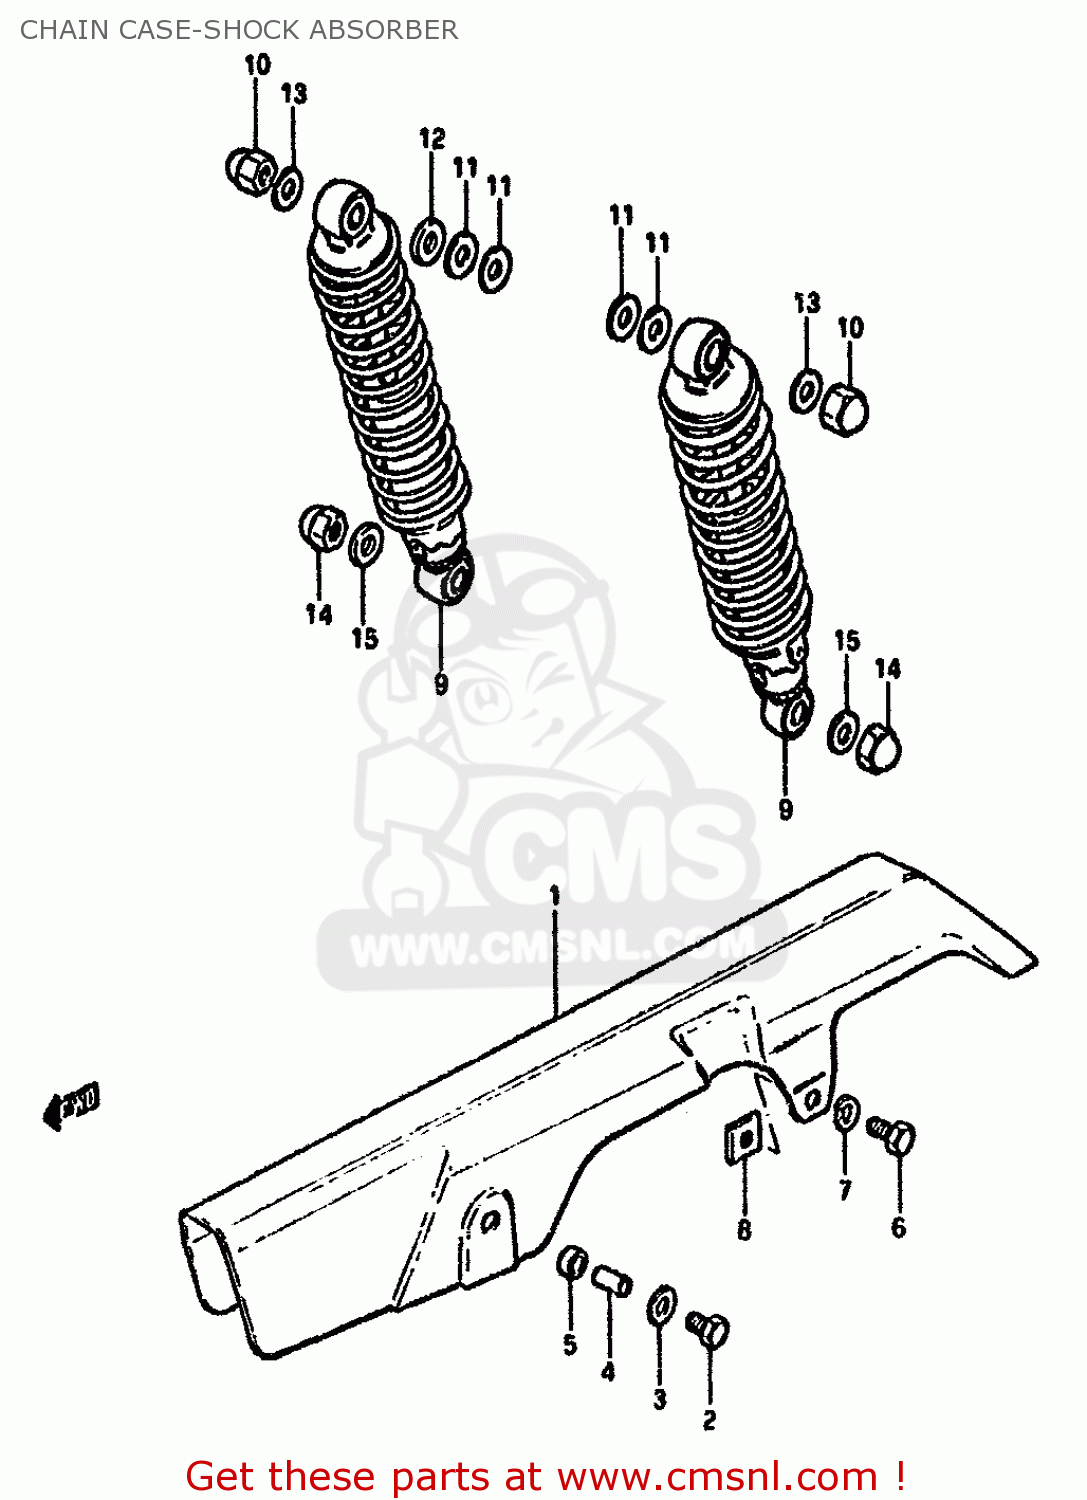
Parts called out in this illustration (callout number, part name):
1	CASE,CHAIN
2	BOLT
3	WASHER(6.5X18X1)
4	SPACER (6.1X8X5.2)
5	CUSHION
6	BOLT, UPPER
7	LOCK WASHER
8	NUT,CHAIN CASE RR
9	SHOCK ABSORBER ASSY
10	NUT
11	WASHER
12	WASHER (12.5X24X3.2)
13	WASHER
14	NUT, LOWER LH
15	WASHER
